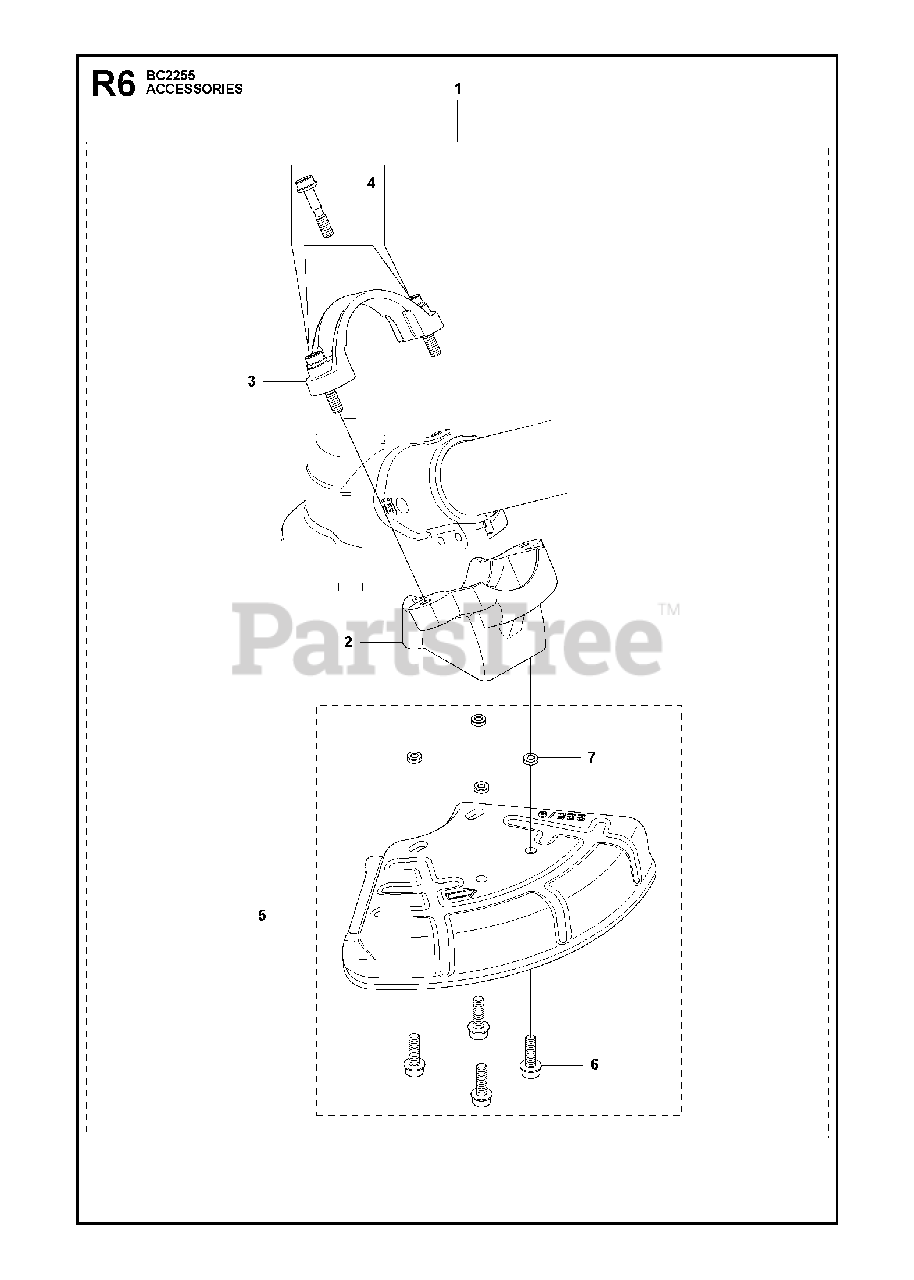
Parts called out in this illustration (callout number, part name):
1	ADAPTER
2	ADAPTER
4	SCREW IHSCFMO
5	BLADE GUARD
6	SCREW
7	LOCKING NUT
